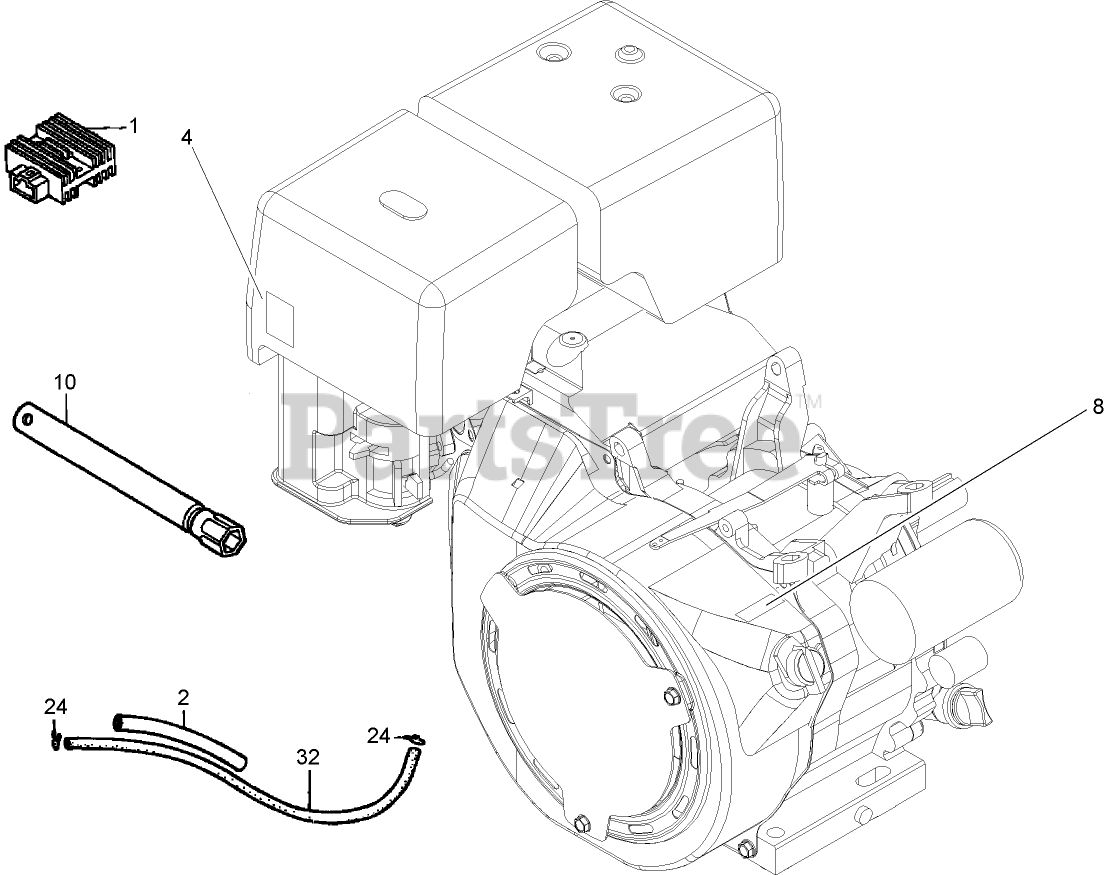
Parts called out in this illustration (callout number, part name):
1	REGULATOR RECTIFIER ASM
2	SUPPORTER-RUBBER (107 mm)
4	MARK-CHOKE (EXTERNAL)
8	MARK, OIL ALERT (E)
10	WRENCH-SPARK PLUG
24	CLIP-TUBE (B8)
32	HOSE-FUEL (4.5X3000) (4.5X235)
